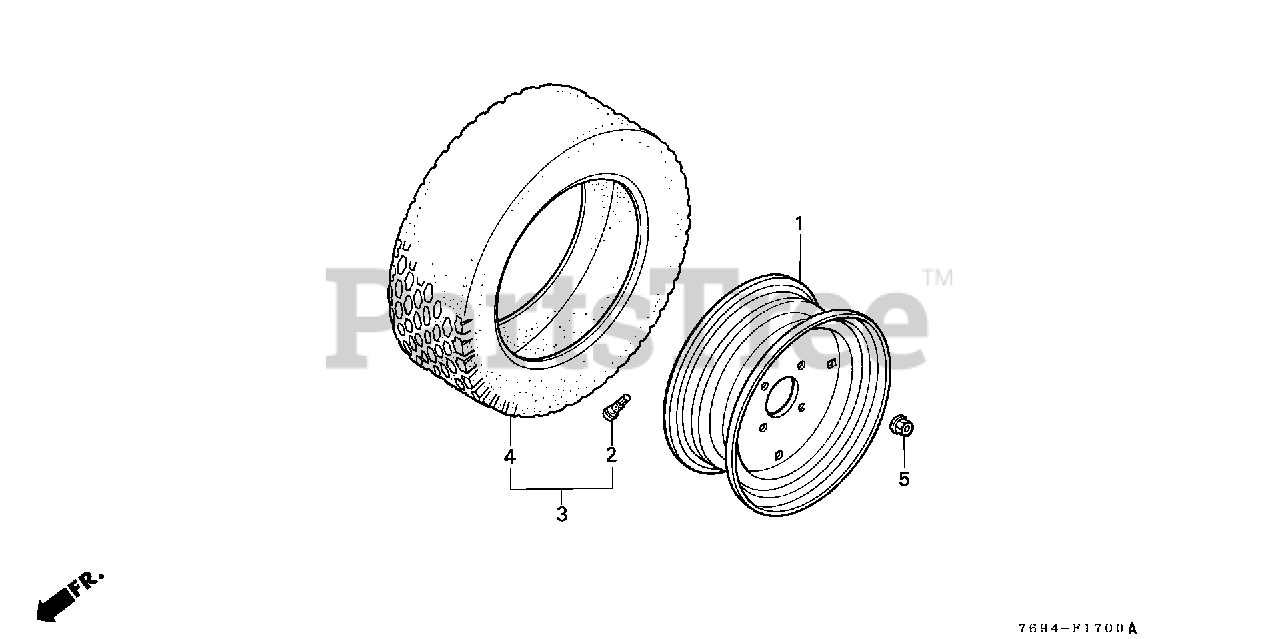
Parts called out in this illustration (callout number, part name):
1	WHEEL (5JAX12WDC) *NH35M* (CLOUD SILVER METALLIC)
1	WHEEL (12X4JA) (WDC)
2	VALVE, RIM
3	TIRE ASSY., FR. (20X7.00-12) (2PR)
4	TIRE, FR. TUBELESS (5-12-4PR)
5	NUT, WHEEL (12MM)
